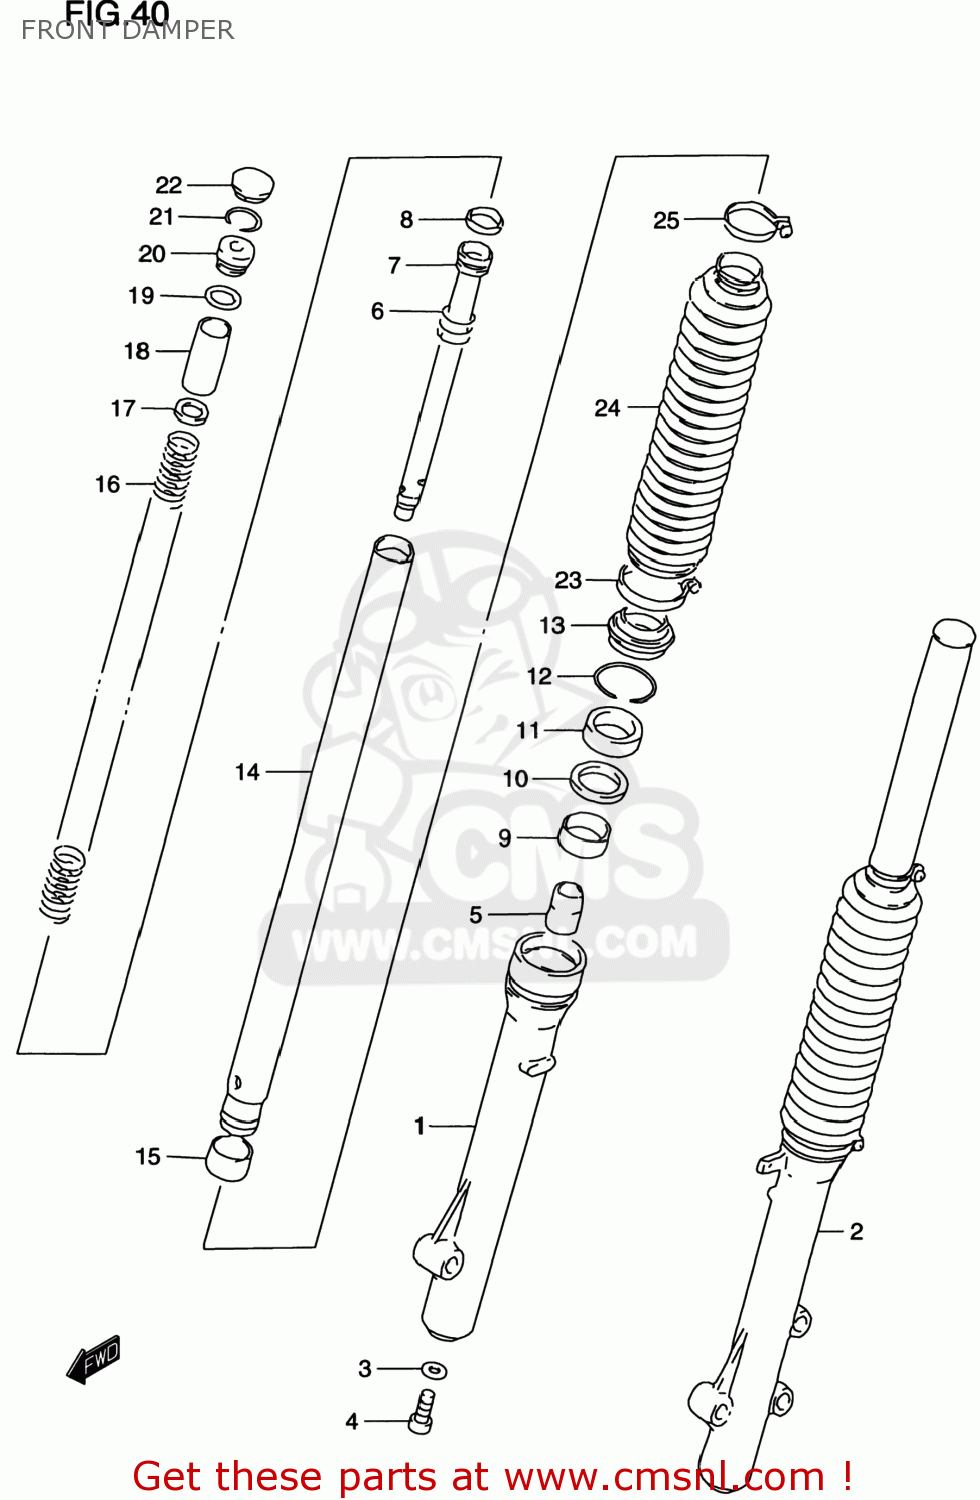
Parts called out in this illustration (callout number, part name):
1	TUBE,OUTER,R
2	TUBE,OUTER,L
3	GASKET (NAS)
4	BOLT,CENTER (8X18)
5	PIECE,OIL LOCK
6	SPRING,REBOUND
7	CYLINDER
8	RING,PISTON
9	BUSH,GUIDE
10	SPACER,SEAL
11	SEAL,OIL 35X48X11
12	RING,OIL SEAL STOPPER
13	SEAL,DUST
14	TUBE,INNER
15	PISTON
16	SPRING,MAIN
17	SPRING,JOINT
18	SPACER,SPRING
19	O RING
20	SPRING SEAT B
21	RING,STOPPER
22	CAP
23	BAND,BOOT LWR
24	BOOT
25	BAND
